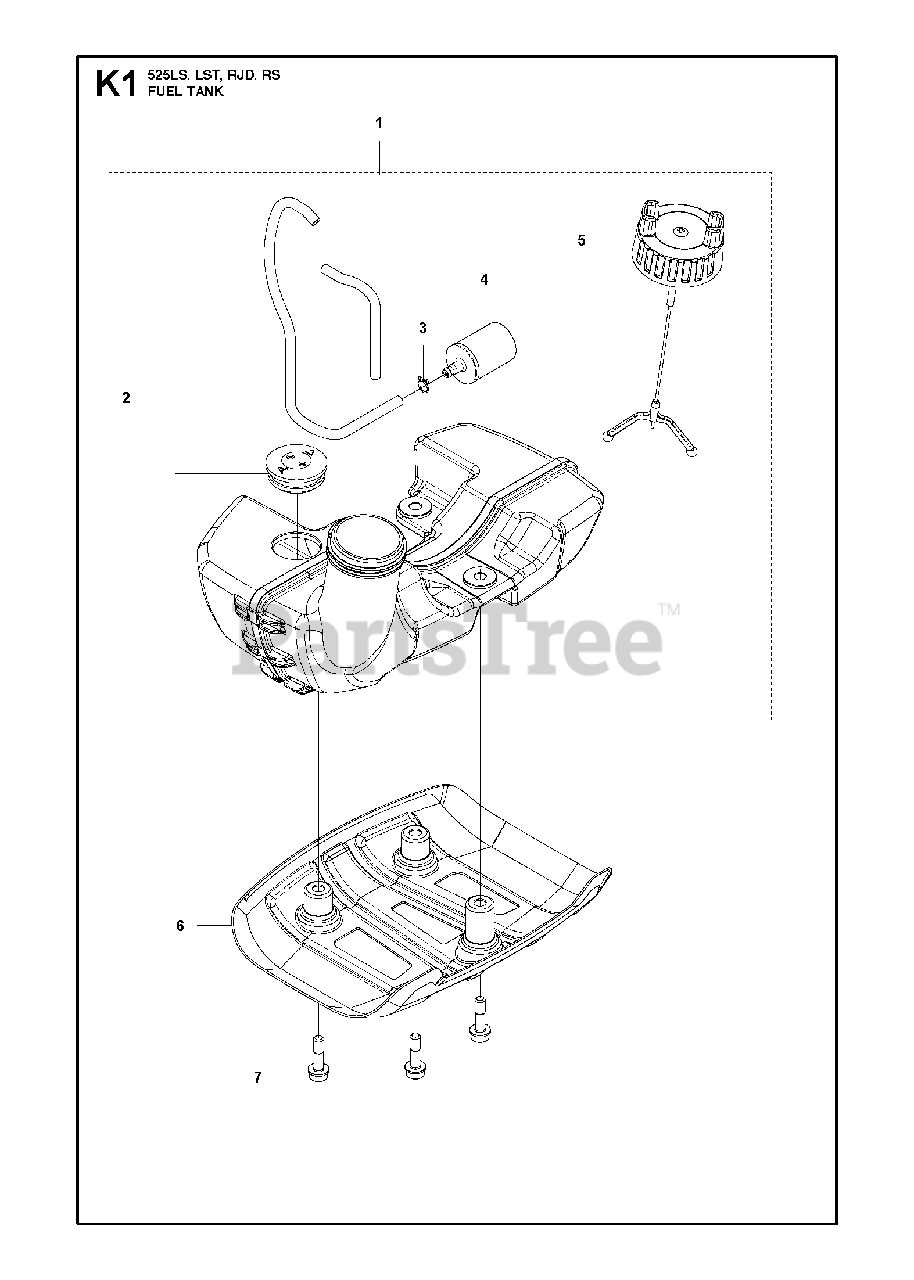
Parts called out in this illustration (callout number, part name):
1	FUEL TANK ASSY
1	FUEL TANK ASSY NBR+PVC
2	HOSE ASSY
2	PIPE
3	CLIP
4	FUEL FILTER
5	TANK CAP COMP
6	SKID PLATE
7	BOLT
